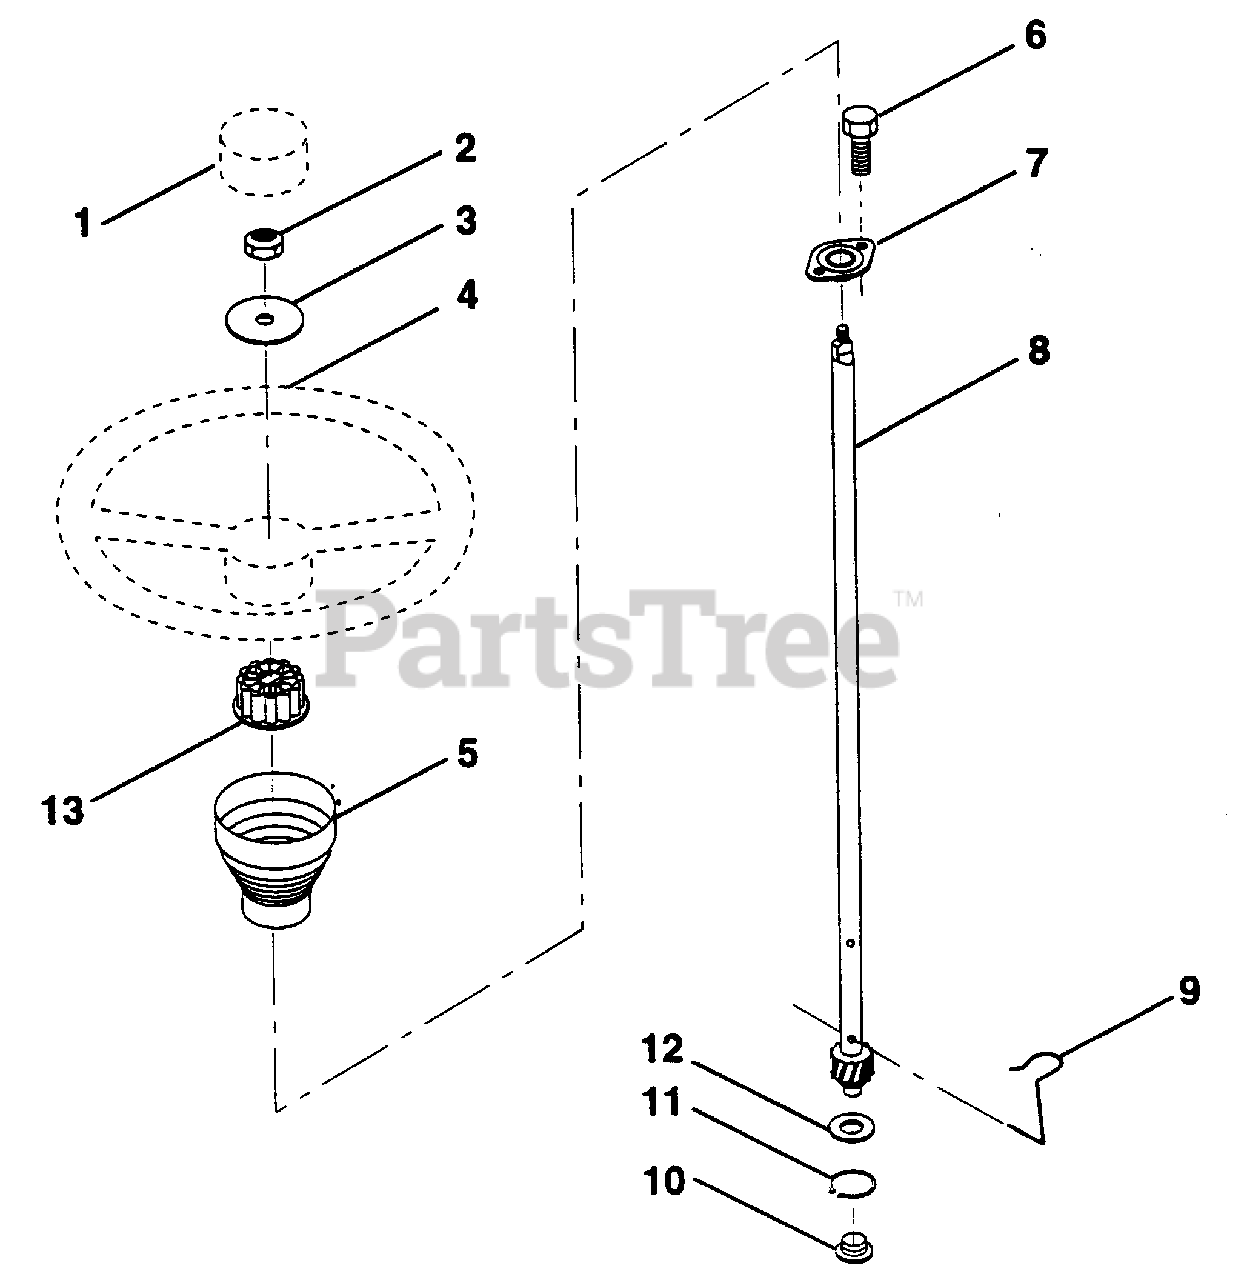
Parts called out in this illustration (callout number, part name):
1	Insert, Steering Wheel (AYP part number)
2	Locknut 3/8-24 UNF (AYP part number)
3	Washer 12/32 x 2-3/8 x 8 Gauge (AYP part number)
4	Steering Wheel (AYP part number)
5	Sleeve, Steering (AYP part number)
6	Screw, Hex Head #10-16 x 1/2 (AYP part number)
7	Bushing, Steering (AYP part number)
8	Shaft, Steering (AYP part number)
9	Clip, Steering (AYP part number)
10	Bushing, Lower, Steering (AYP part number)
11	Ring, Retaining (AYP part number)
12	Washer 21/32 x 1 x 16 Gauge (AYP part number)
13	Adaptor, Steering Wheel (AYP part number)
